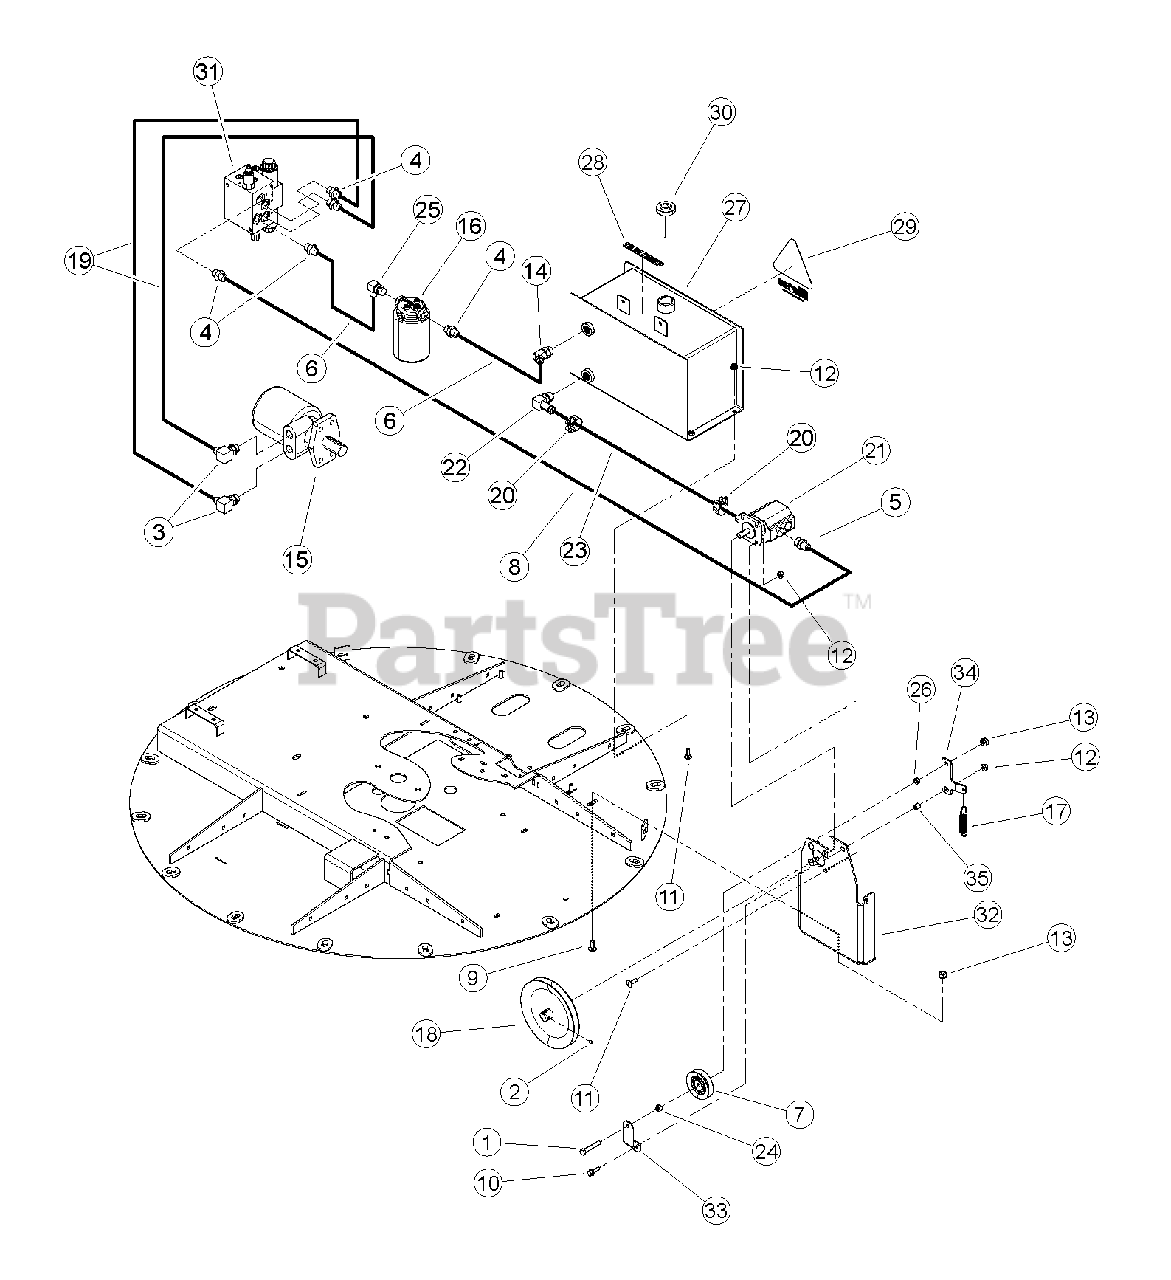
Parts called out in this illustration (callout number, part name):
1	BOLT, 3/8 X 2-1/4 HEX GR5 ZP
2	SET SCREW, HSC 1/4 -20X -3/8 CUP
3	ADAPTER, -10MORING/-8MJIC 90 DEG
4	ADAPTER, -8MORING/-8MJIC
5	ADAPTER, -10MORING/-8MJIC
6	HOSE ASSEMBLY, 8FMJIC/8FMJIC SW X 32"
7	IDLER, INSIDE
8	HOSE ASSEMBLY, 8FJIC90 SW X 8FJIC SW 54"
9	BOLT, 3/8 X 1" GR5 CRG NC ZP
10	BOLT, 5/16 X 1 FLANGE NC
11	BOLT, 5/16 X 1" GR5 CRG ZP
12	NUT, 5/16-18 NYLOCK-FLANGE
13	NUT, 3/8-16 NYLOCK FLANGE
14	ADAPTER, -10MORING/-8MJIC 45 DEG
15	MOTOR, 45 CU IN HYDRAULIC
16	ASSEMBLY, HYDRAULIC FILTER
17	SPRING, 3/4" OD EXTENSION
18	PULLEY, 7.5 OD X 1/2 IN BORE
19	HOSE ASSEMBLY, -8FMJIC/-8FMJIC90 X 61
20	CLAMP, 1-5/32 TO 7/32 OD RANGE T-BOLT
21	PUMP, 2 STAGE CW HI/LO 0.605 DISP.
22	ADAPTER, -10 MORING/.75 90 DEG HOSE
23	HOSE, .75 X 19.75 100R4
24	BUSHING
25	ADAPTER, -8MORING/-8MJIC 90 DEG
26	SPACER, IDLER PIVOT
27	ASSEMBLY, HYDRAULIC TANK SERVICE PART
28	DECAL, HYDRAULIC FLUID
29	DECAL, CHIP IT (WHITE)
30	CAP, HYDRAULIC W/ DIPSTICK
31	ASSEMBLY, HYDRAULIC FEED FLOW VALVE W/ PS
32	WELDMENT, PUMP MOUNT
33	BRACKET, IDLER MOUNT
34	PLATE, IDLER MOUNT
35	SPACER, 1/2 OD X 14 GA X .49
